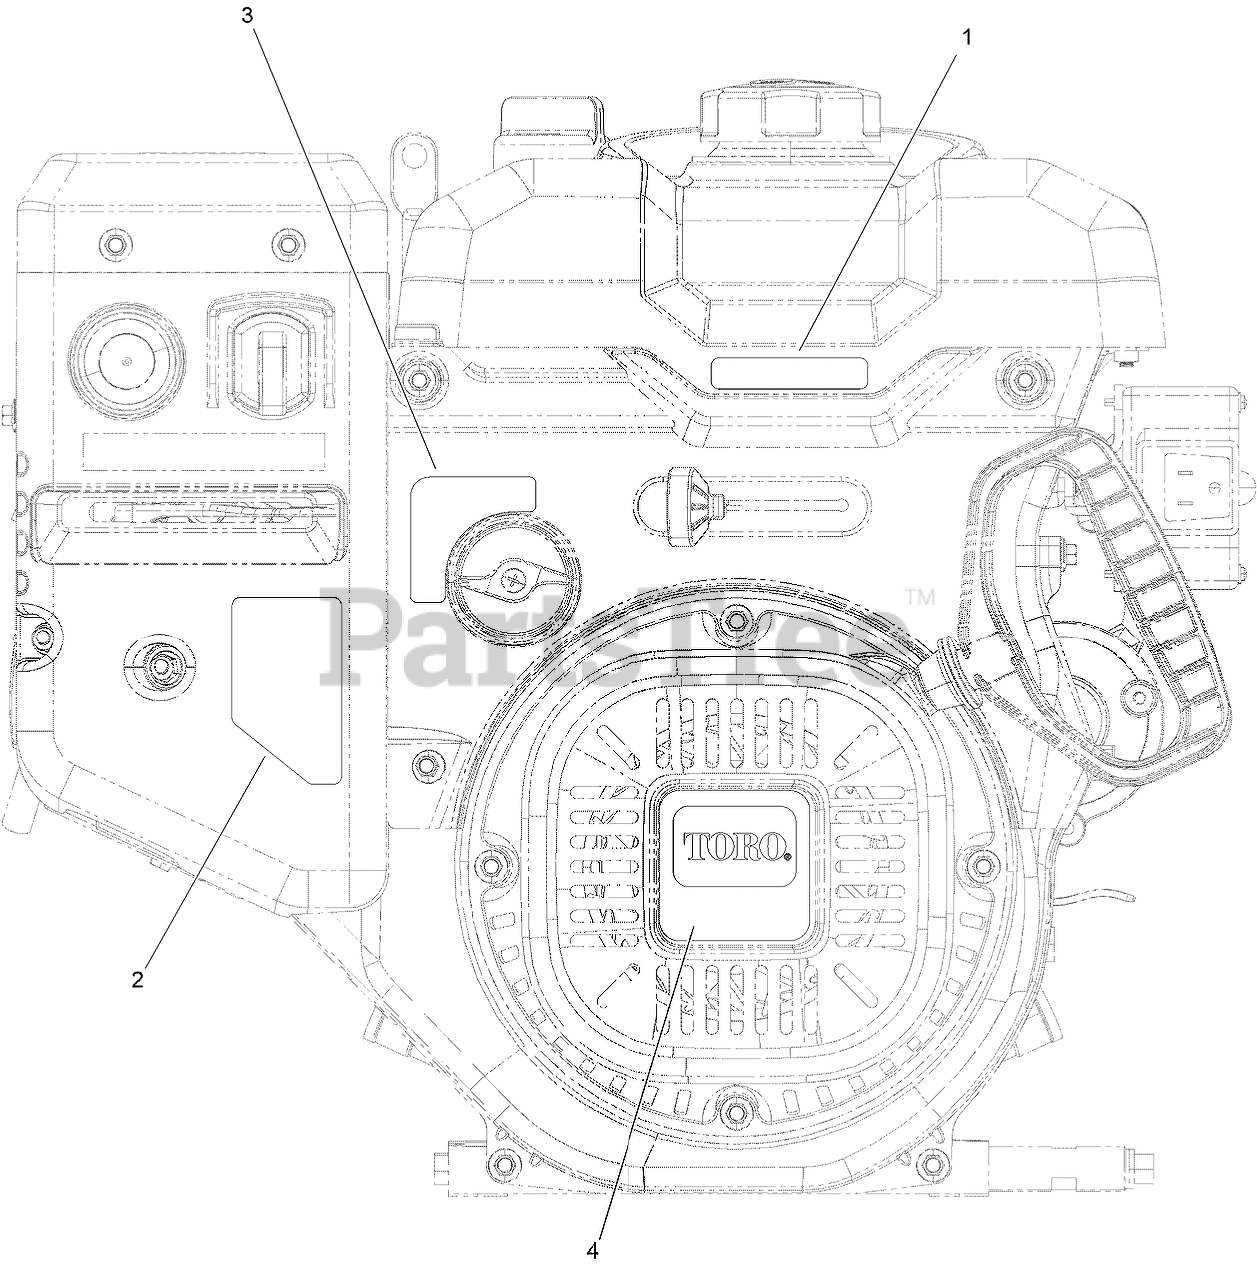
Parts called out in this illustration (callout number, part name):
1	DECAL-THROTTLE
2	DECAL-CONTROL, ENGINE
3	DECAL-VALVE, FUEL
4	DECAL-RECOIL
